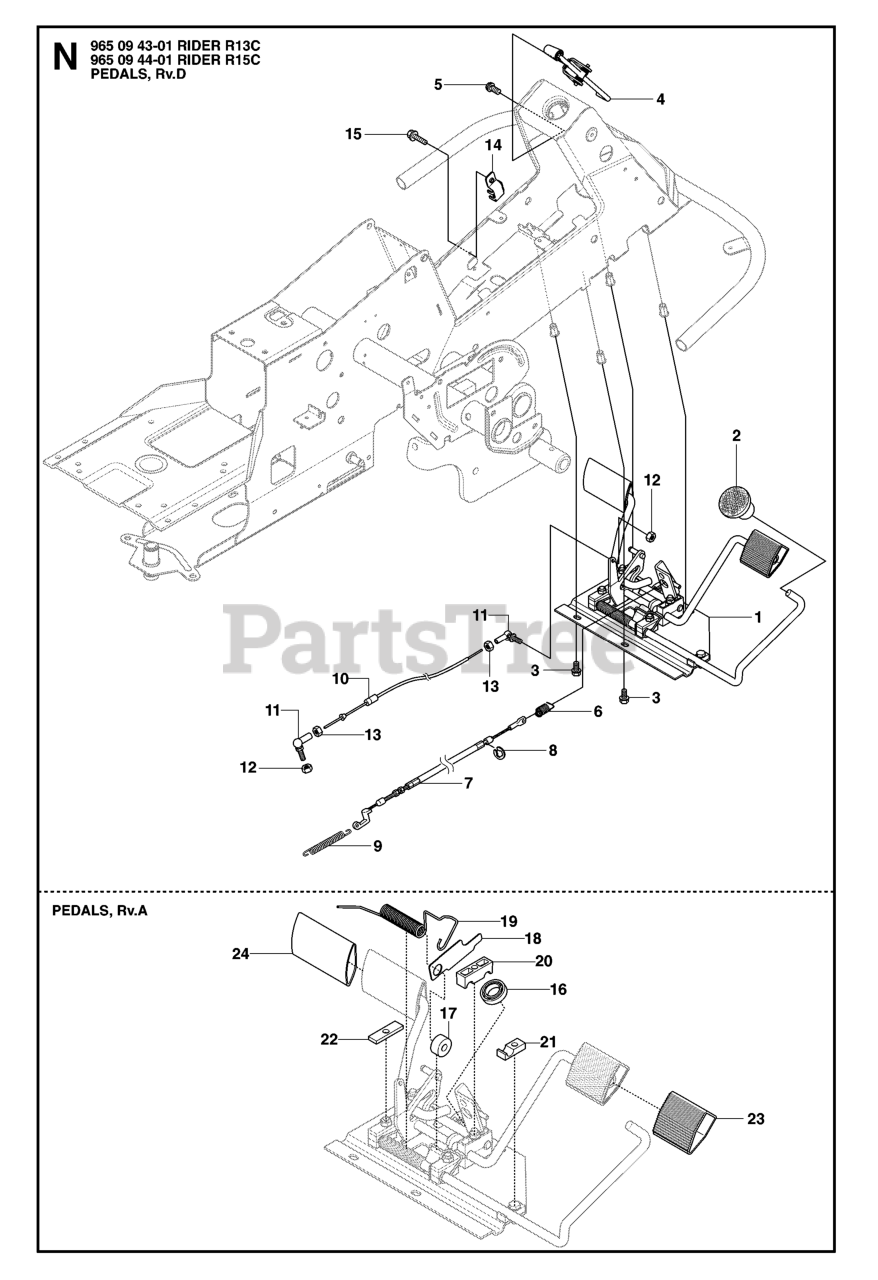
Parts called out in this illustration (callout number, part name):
1	PEDAL ASSEMBLY
2	KNOB
4	BRAKE LEVER ASSY
7	BRAKE WIRE
10	%WIRE
11	CONNECTOR
12	LOCKNUT M5
14	BRACKET
16	BALL BEARING 6002-2RS1
17	ROLLER
18	PLATE
19	SPRING
20	PEDAL SHAFT CLAMP
21	SUPPORT
22	PLATE
23	PEDAL RUBBER
24	PEDAL RUBBER, SF
